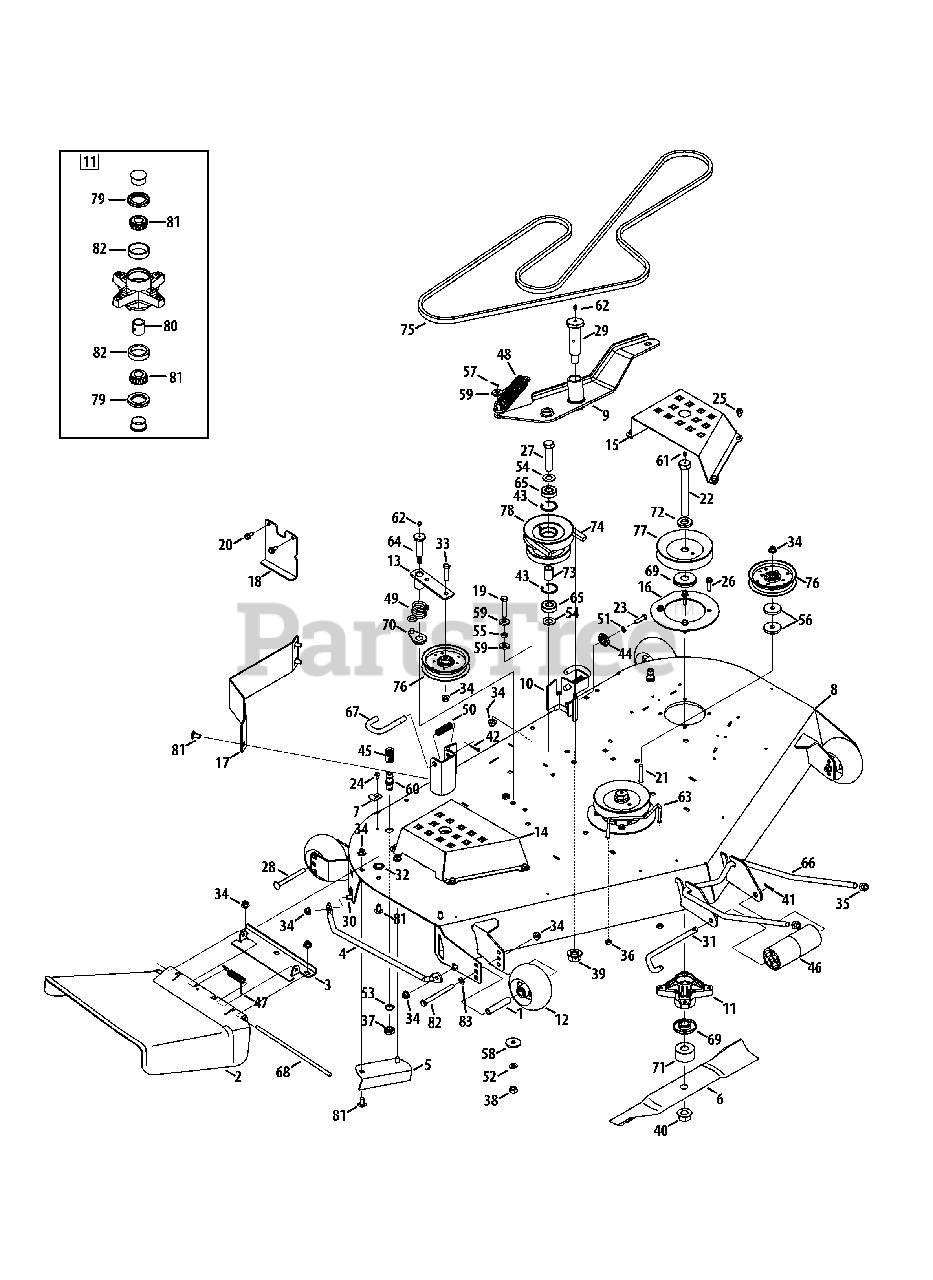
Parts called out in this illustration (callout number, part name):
1	Spacer, .390 x .620 x 3.04
2	Chute Deflector
3	Chute Deflector Bracket
4	Finger Guard
5	Micor Chute Baffle
6	Hi-Lift Blade, 19
7	Hook Retainer Bracket
8	Deck Assembly
10	Hanger Adjustment Bracket
11	Spindle Assembly
12	Wheel, 5.0
16	Spindle Reinforcement Plate
17	Baffle
18	Up-Stop Bracket
19	Hex Screw, 3/8 x 16 x 1.75
20	Hex Washer Screw, 5/16-18 x .750
21	Carriage Bolt, 3/8-16 x 2.50
22	Hex Screw, 3/4-16 x 6.00
23	Hex Screw, 5/16-18 x 1.25
24	Hex Washer Screw, 1/4-20 x .500
25	Hex Washer Screw, 5/16-18 x .625
26	Hex Washer Screw, 5/16-18 x 1.50
27	Hex Screw, 5/8-18 x 3.00
28	Carriage Screw, 3/8-16 x 4.00
29	Shoulder Screw, 1.0 x 3.00
30	Carriage Bolt, 3/8-16 x 1.00
31	Roller Pin, 1/2 x 7.31
32	Push Nut, 3/8
33	Hex Screw, 3/8-16 x 1.50
34	Flange Lock Nut, 3/8-16
35	Flex Lock Nut, 1/2-13
36	Hex Lock Nut, 1/4-20
37	Hex Nut, M16-1.5
38	Hex Nut, 7/16-14
39	Flange Lock Nut, 5/8-18
40	Flange Lock Nut, 3/4-16
41	Cotter Pin, 3/32 x 1.25
42	Cotter Pin, 5/32 x 1.25
43	Retainer Ring
44	Deck Adjustment Gear
45	Water Nozzle Adapter
46	Front Roller
47	Torsion Spring, 180 x .639 x 2.16 x .12
48	Extension Spring, 1.25 x 6.9
49	Idler Torsion Spring, 1.10 x 1.3
50	Compression Spring, .66 x 1.8
51	Lock Washer, 5/16
52	Lock Washer, 7/16
53	Lock Washer, 5/8
54	Flat Washer, .650 x 1.250 x .075
55	Jam Nut, 3/8-16
56	Flat Washer, .4375 x 1.75 x .25
57	Cotter Pin, 3/32 x .750
58	Flat Washer, .45 x 1.5 x .172
59	Falt Washer, .385 x 1.00 x .135
60	Deck Water Nozzle
61	Grease Fitting, 1/4-28 x 3/16
62	Drive Lube Fitting, 3/16
63	Belt Drive Guard
64	Shoulder Screw, 7/16-14 x .687 x 2.443
65	Ball Bearing, .625 x 40 x 12
66	Front Hanger Rod
67	Mower Support Pin
68	Chute Deflector Rod
69	Spindle Deck Spacer
70	Retainer Spring
71	Spindle Spacer, .760 x 2.0 x 1.10
72	Spacer, .812 x .218
73	Spacer, .88 x .635 x 1.25
76	Idler Pulley
78	Double Pulley
80	Bearing Spacer, .78 x 1.0 x 1.0425
81	Cone Bearing, .750
81	Carriage Bolt, 3/8-16 x .75
82	Bearing Cup, .750
82	Hex Screw, 3/8-16 x 4.00
83	Washer, .375 x .700 x .030
